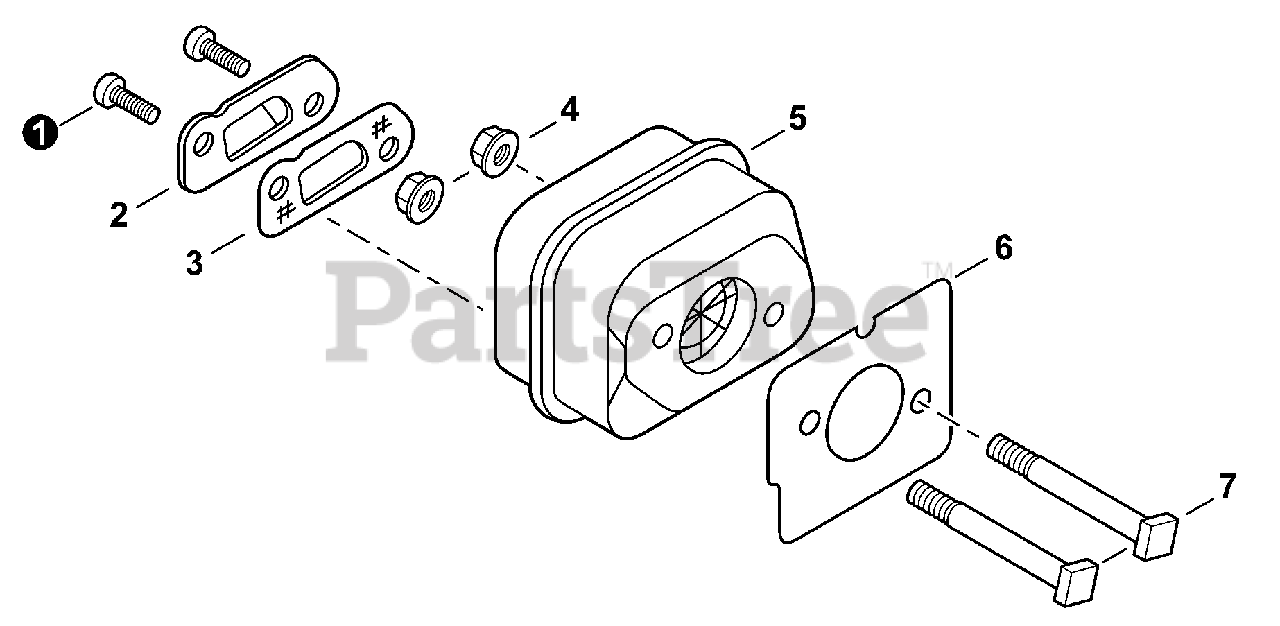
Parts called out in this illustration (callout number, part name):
1	BOLT, TORX 4×8
2	GUIDE, EXHAUST
3	SCREEN, SPARK ARRESTER
4	NUT, FLANGE M5
5	MUFFLER
6	GASKET, EXHAUST
7	BOLT 5×60
